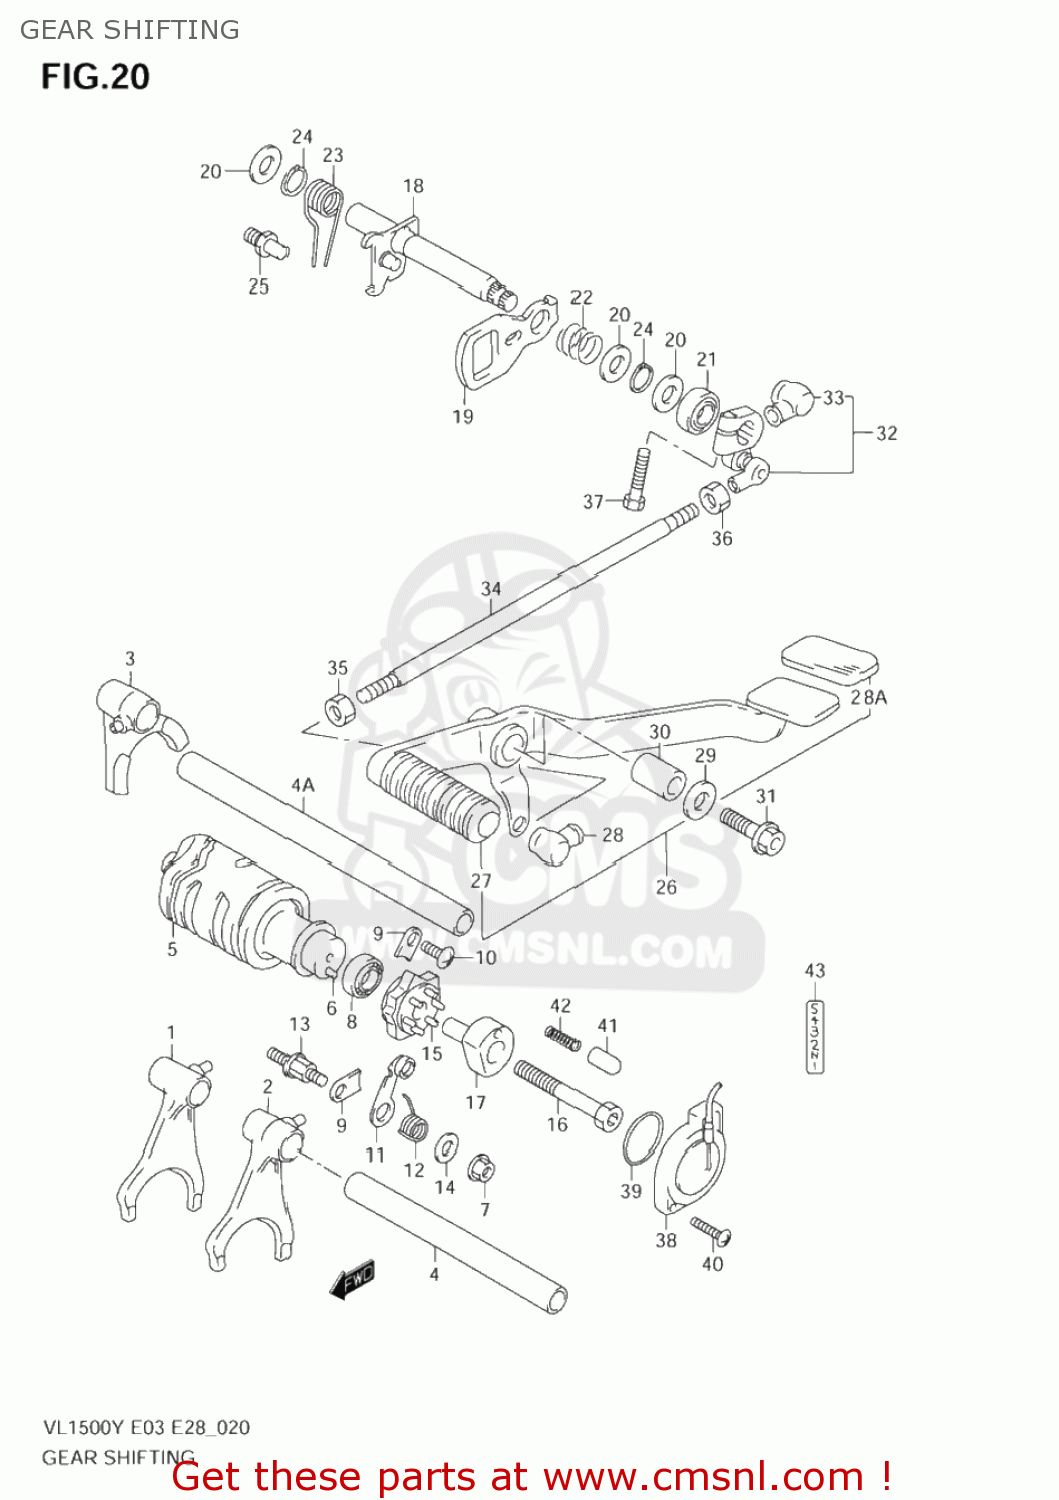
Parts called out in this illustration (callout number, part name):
1	FORK,GEAR SHIFT NO.1
2	FORK,GEAR SHIFT NO.2
3	FORK,GEAR SHIFT NO.3
4	SHAFT,GEAR SHIFT FORK NO.1
4A	SHAFT GEAR SHIFT FORK NO.2
5	CAM,GEAR SHIFT
6	PIN
7	NUT
8	BEARING(25X47X8)
9	RETAINER,BEARING
10	SCREW
11	STOPPER,GEAR SHIFT CAM
12	SPRING,SHIFT CAM STOPPER
13	SUPPORT,CAM STOPPER ARM
14	WASHER
15	PLATE,GEAR SHIFT CAM
16	BOLT(6X50)
17	HOLDER,NEUTRAL SWITCH
18	SHAFT,GEAR SHIFT
19	PLATE,GEAR SHIFT CAM DRIVE
20	SHIM(14X22X1)
21	SEAL,OIL(14X22X6)
22	SPRING
23	SPRING
24	CIRCLIP
25	STOPPER,GEAR SHIFT CAM
26	LEVER ASSY,GEAR SHIFT
27	RUBBER
28	COVER,DUST
28A	RUBBER,BRAKE PEDAL
29	WASHER (10.5X24X2.3)
30	SPSCER,GEAR SHIFT LEVER
31	BOLT(10X40)
32	ARM,GEAR SHIFT LINK
33	COVER,DUST
34	ROD,GEAR SHIFT LINK
35	NUT
36	NUT 6MM
37	BOLT
38	BASE ASSY,NEUTRAL SW TERMINAL
39	O RING(D:2.4,ID:35.5)
40	SCREW
41	PIN
42	SPRING
43	LABEL,GEAR SHIFT
